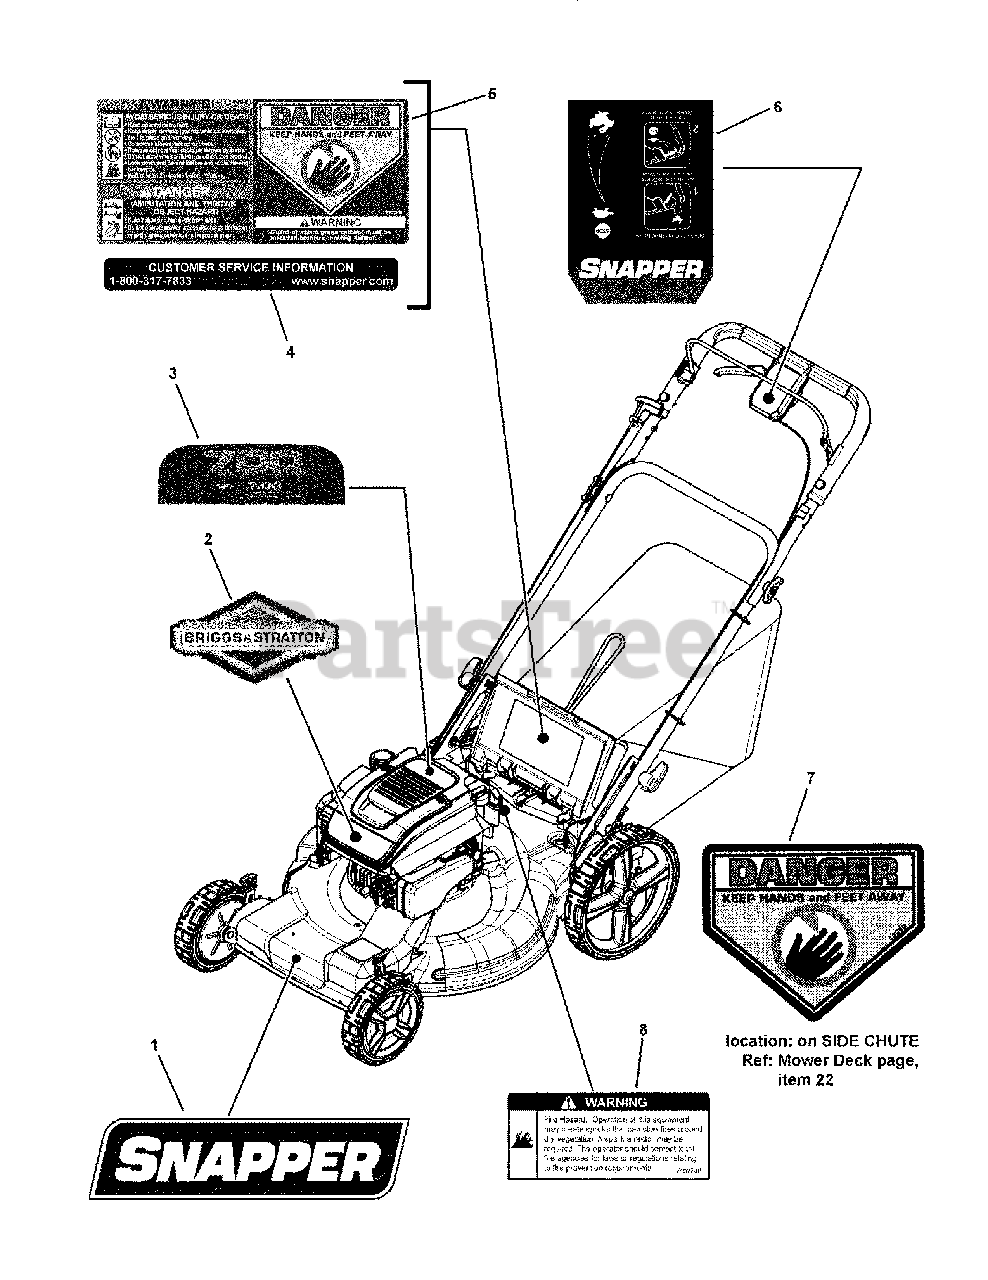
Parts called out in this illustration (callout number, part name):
1	DECAL, Front Shroud, SNAPPER Logo
2	* DECAL, Briggs Engine, B&S Logo
3	DECAL, Briggs Engine, 700 Series
4	DECAL, Customer Service
5	DECAL, WARNING, Rear Discharge Door
6	DECAL, Control Head, VS SNAPPER
7	DECAL, DANGER, Cut Finger
8	DECAL, Spark Arrestor
